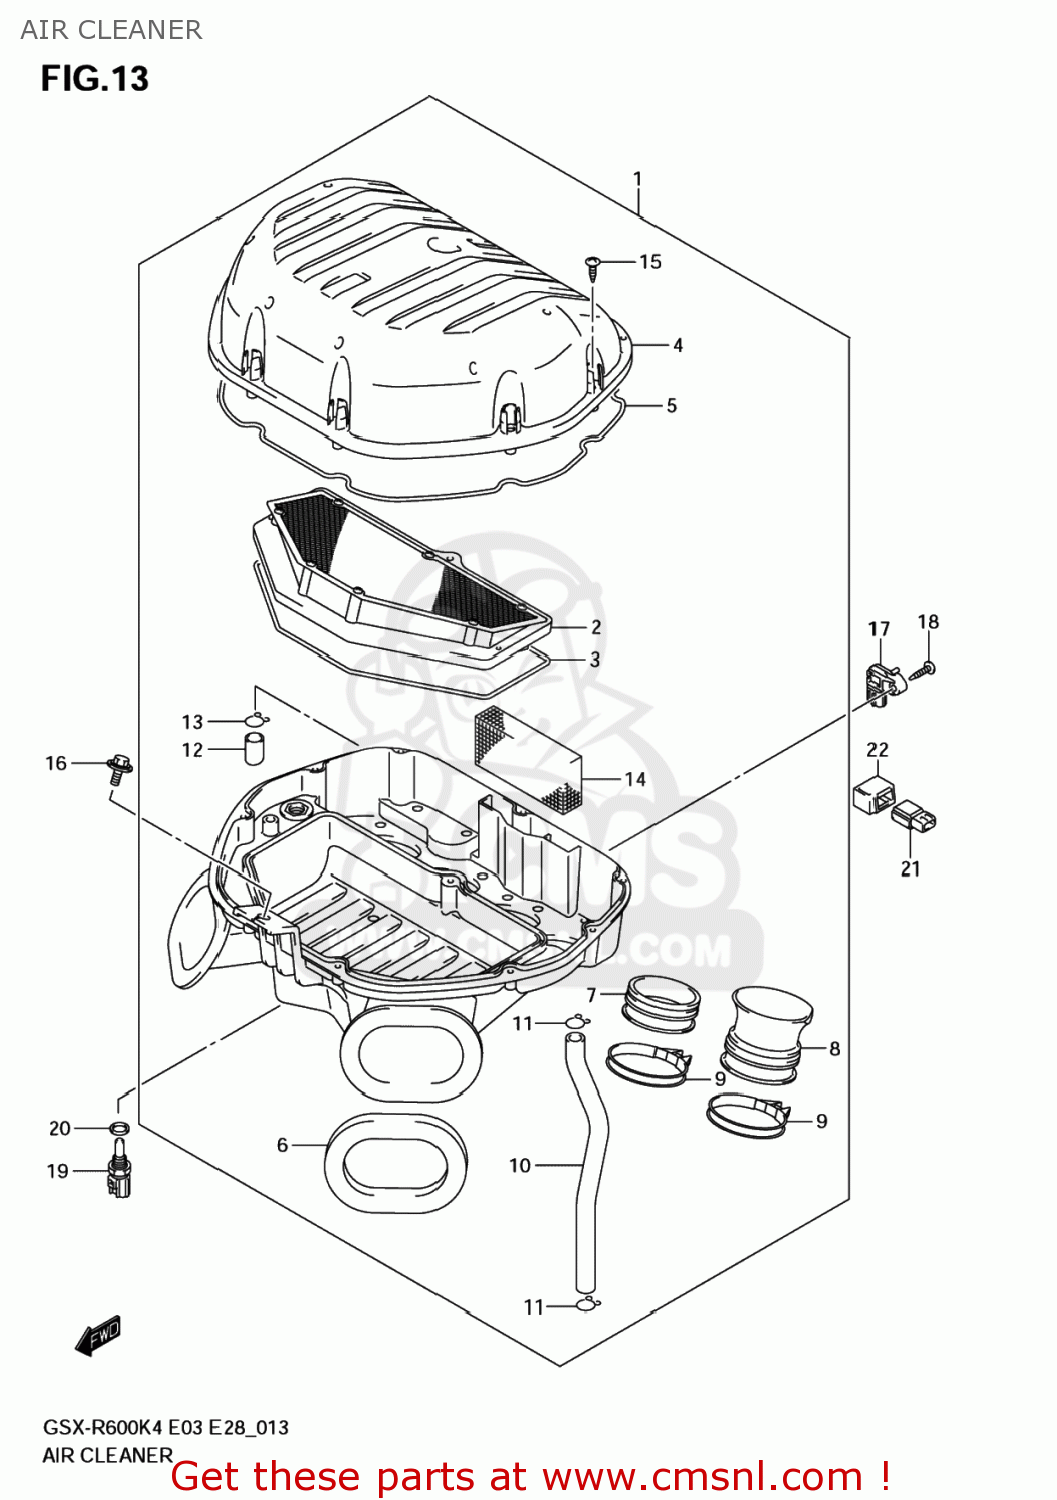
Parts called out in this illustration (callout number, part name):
1	CLEANER ASSY,AIR
2	FILTER ASSY
3	GASKET,CASE (NAS)
4	CAP,AIR CLEANER
5	GASKET,CAP (NAS)
6	CUSHION
7	TUBE,OUTLET A
8	TUBE,OUTLET B
9	CLAMP
10	TUBE,BREATHER
11	CLIP
12	PLUG
13	CLIP
14	FILTER,BREATHER
15	SCREW
16	BOLT(6X16)
17	SENSOR,BOOST
18	SCREW
19	SENSOR,WATER TEMP
20	GASKET(12X17X1) (NAS)
21	SENSOR,AIR PRE
22	COVER
